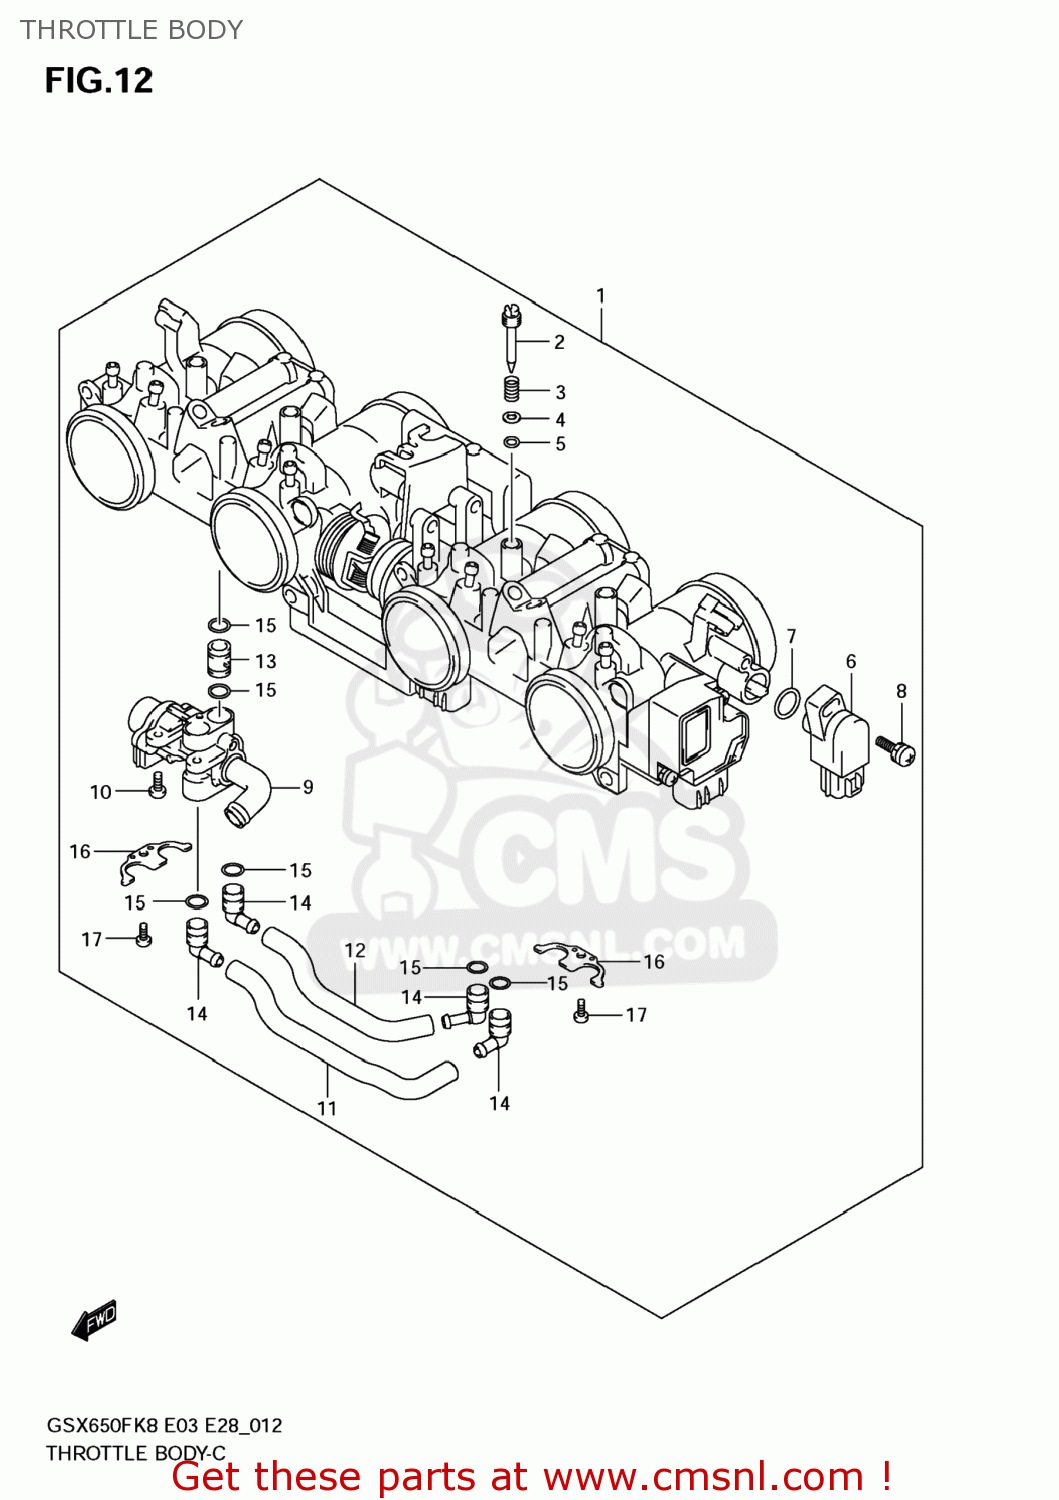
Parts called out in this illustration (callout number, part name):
1	BODY ASSY,THROTTLE
2	SCREW
3	SPRING,THROTTLE SCREW
4	WASHER
5	O RING,PILOT AIR SCREW
6	SENSOR
7	O RING
8	SCREW
9	ACTUATOR
10	SCREW
11	HOSE
12	HOSE
13	PIPE
14	NIPPLE
15	O RING
16	PLATE
17	SCREW
